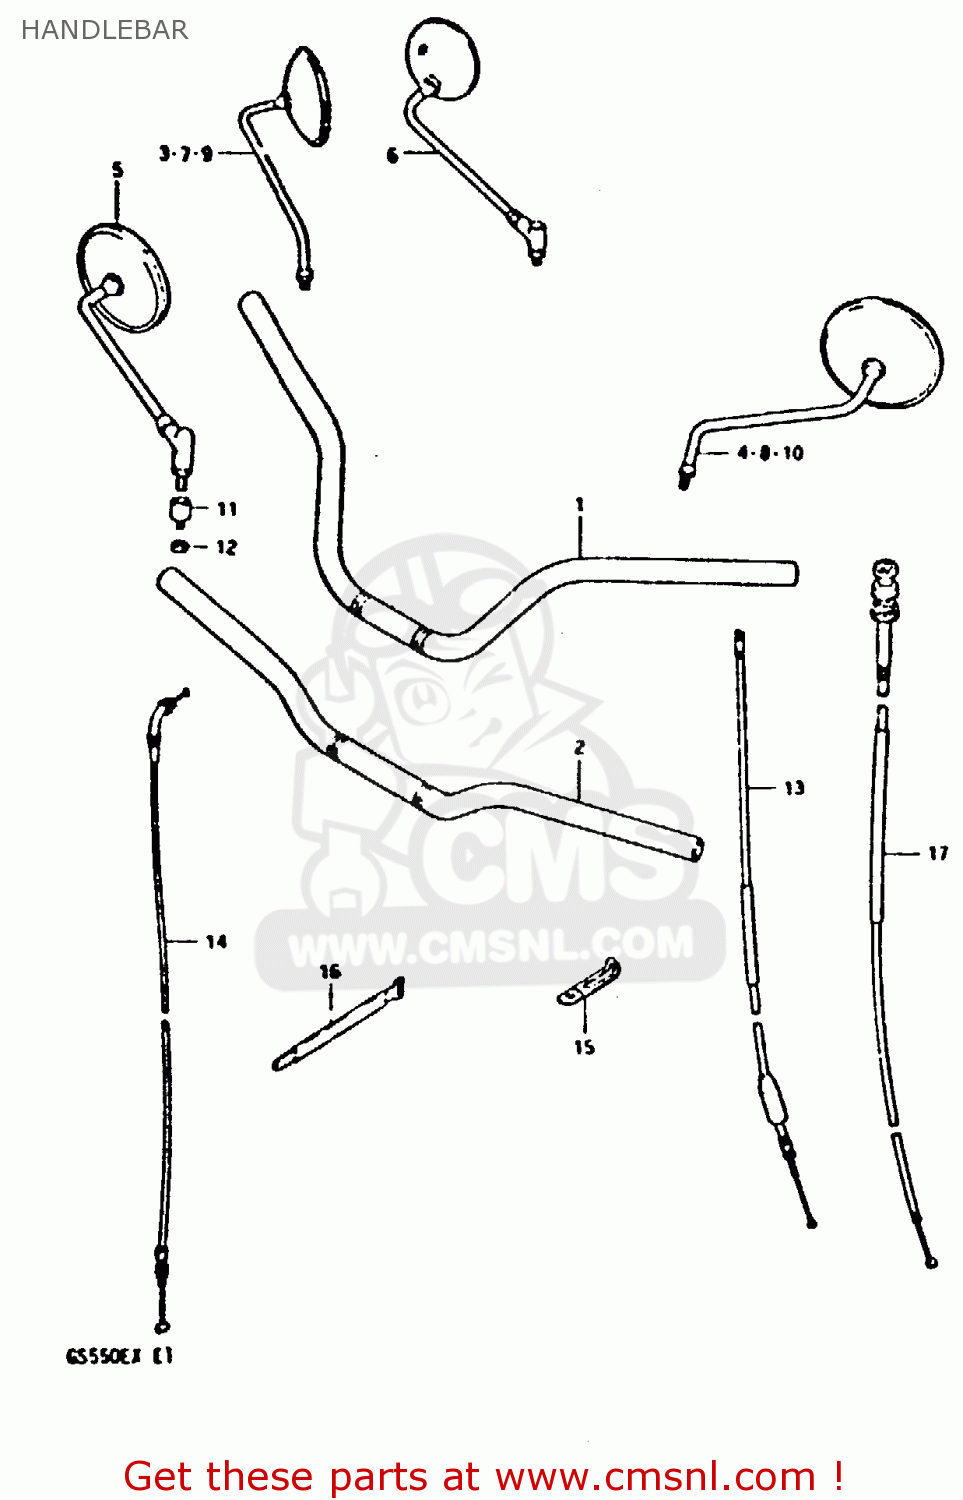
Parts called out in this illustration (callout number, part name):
1	HANDLEBAR (NERTRAL)
2	HANDLEBAR (FLAT)
5	MIRROR ASSY,RH
11	CUSHION,REAR VIEW MIRROR
12	NUT
13	CABLE ASSY,CLUTCH
14	CABLE ASSEMBLY,THROTTLE
15	CLAMP
16	CLAMP
17	CABLE ASSEMBLY,STARTER
